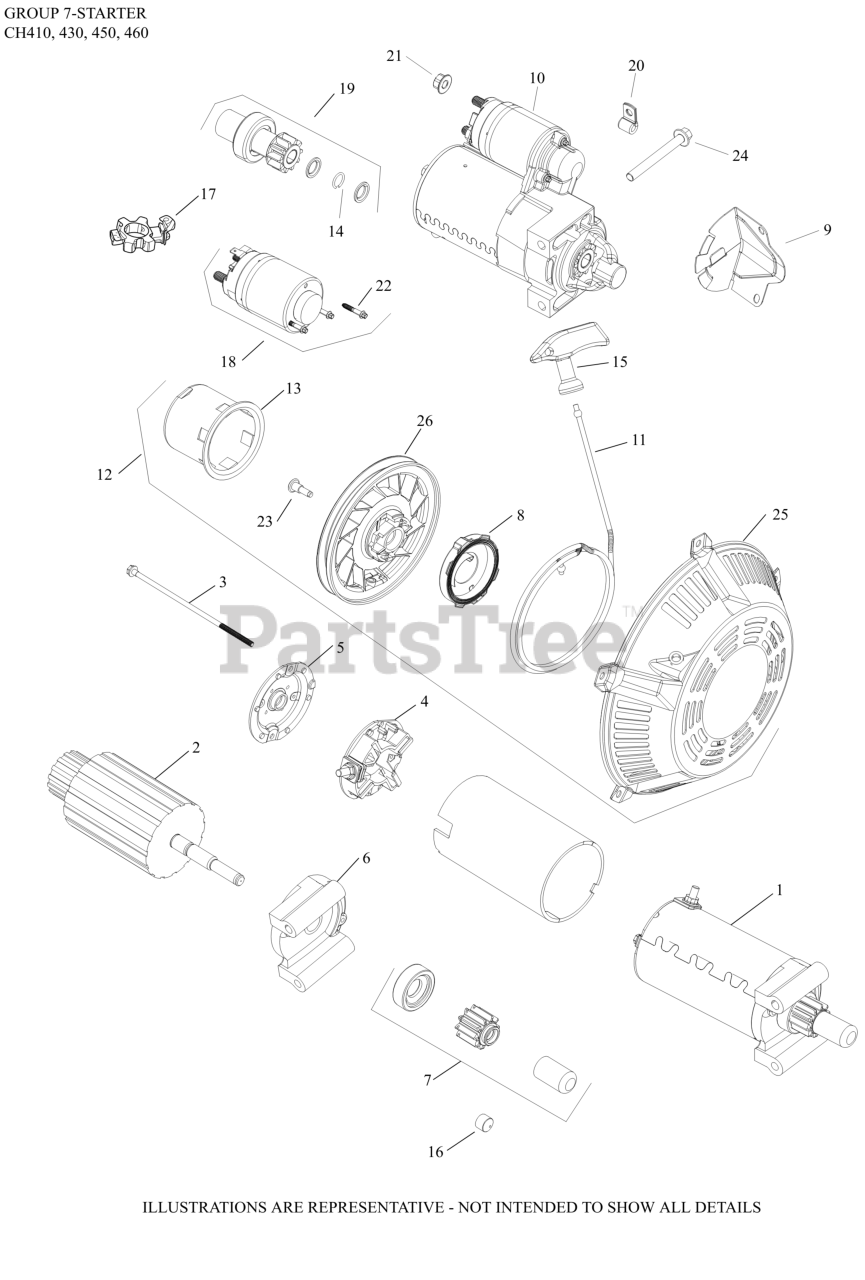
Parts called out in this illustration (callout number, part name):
8	SPRING & KEEPER - DISCONTINUED
9	COVER, STARTER MOTOR
11	ROPE-(#DSC)
12	STARTER,RETRACTABLE-USE 12 165 03-S
15	HANDLE, RECOIL STARTER
23	SCREW-(#DSC)
25	HOUSING-(#DSC)
26	PULLEY - DISCONTINUED
NI	KIT, DOG REPAIR - DISCONTINUED
